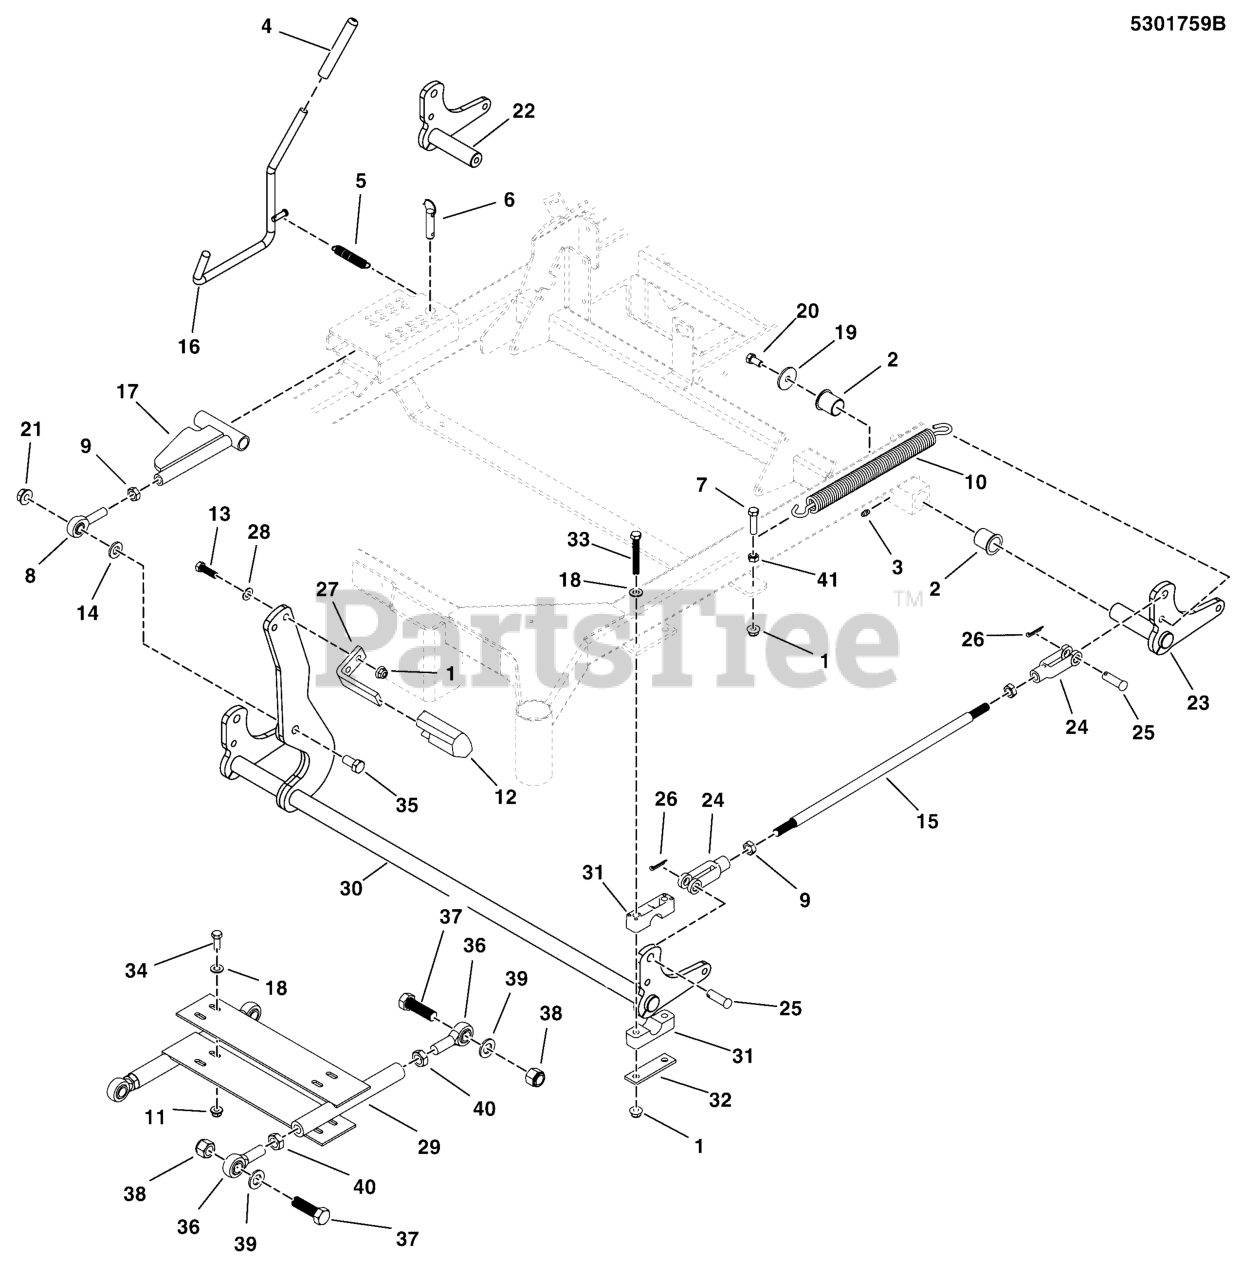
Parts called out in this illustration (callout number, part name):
1	NUT, 3/8 - 16 HEX NYLOCK FLANGE
2	BUSHING, 1.00 X 1.13 X 1.38, Plastic
3	GREASE FITTING, 1/4-28 Straight
4	GRIP, FOAM, .475 X 4.35 X .095
5	SPRING-EXT, .500 OD X 3.50 LG X .058 WR
6	PIN, HITCH, 1/2 X 2.00 OAL, YP
7	BOLT, 3/8-16 X 1-1/2" GD5 CZ
8	BALL JOINT, 1/2-20, MALE
9	NUT, 1/2-20 Hex Jam
10	SPRING-EXT, 1.00 ODX13.25LGX.177WR, BLK
11	NUT, 3/8-16 Hex Large Serrated Flange
12	PEDAL, Rubber
13	BOLT, 3/8-16 X 1-1/4" GD5 CZ
14	SPACER, .52 X 1.00 X .22, PM, CZ
15	ROD, DECK LIFT, 19.25, CZ
16	WELD, ROD DECK LIFT, F320Z - BLK
17	WELD, DECK ADJUST LINK - BLK
18	WASHER, 3/8 SAE
19	WASHER, .390 X 1.50 X .109, YZ
20	BOLT, 3/8-16 X 3/4, PLT W/PATCH
21	NUT, Hex Flange, Nylock, 1/2-13
22	WELD, PIVOT, DECK LIFT, RH - 210 - BLK
23	WELD, PIVOT, DECK LIFT, LH - 210 - BLK
24	CLEVIS, 1/2-20, STEEL, CLEAR ZINC
25	PIN, CLEVIS, 1/2 X 1-1/2, PLATED
26	* PIN, COTTER, 1/8" X 3/4
27	PEDAL, FOOT - BLK
28	WASHER, 3/8" GR. 9 FLAT
29	WELD, DECK STABILIZER, IS2500Z-246 - BLK
30	WELD, DECK LIFT SHAFT, 210Z-200XT - BLK
31	PIVOT BLOCK, PLASTIC
32	PLATE, PIVOT BLOCK SUPPORT - BLK
33	BOLT, 3/8-16 X 2-3/4" GD5 CZ
34	BOLT, 3/8-16 X 1" GD5 CZ
35	BOLT, 1/2-13 X 2-1/4" GD5 CZ
36	BALL JOINT, 3/4-16, MALE
37	BOLT, 3/4-16 X 2-1/2" YZ GD5
38	NUT, Hex, Nylon Lock, 3/4-16
39	WASHER, 3/4 SAE
40	NUT, Hex, Jam, 3/4-16
41	NUT, 3/8-16 HEX JAM
